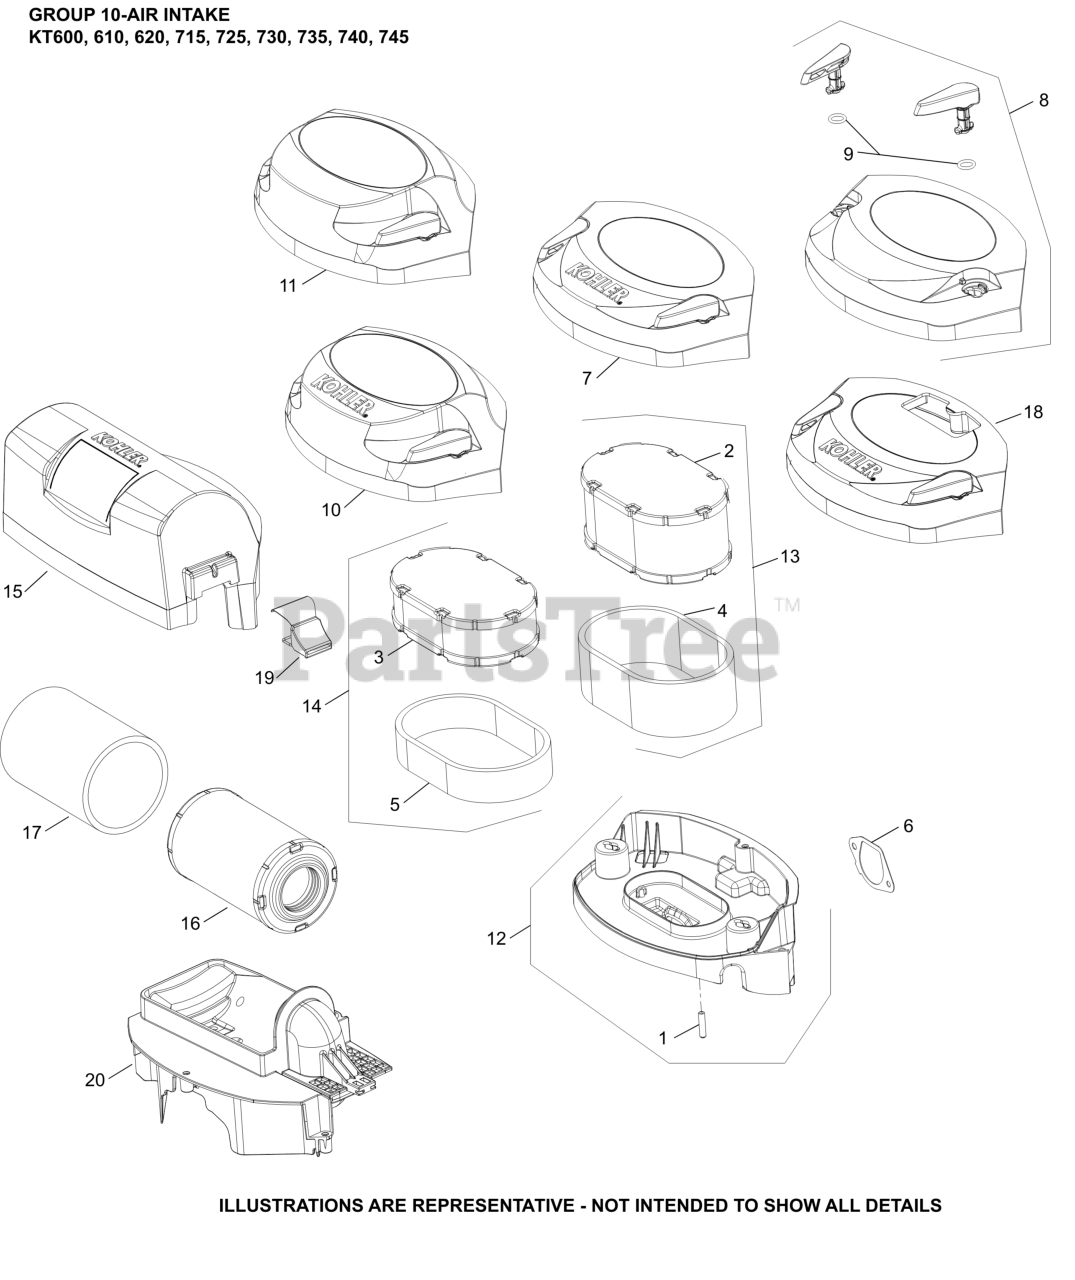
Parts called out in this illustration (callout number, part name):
1	CAP, MASKING
3	ELEMENT, AIR FILTER
5	ELEMENT, PRE-CLEANER
6	GASKET, AIR CLEANER BASE
7	COVER ASSEMBLY, AIR CLEANER
12	BASE ASSY, AIR CLEANER
